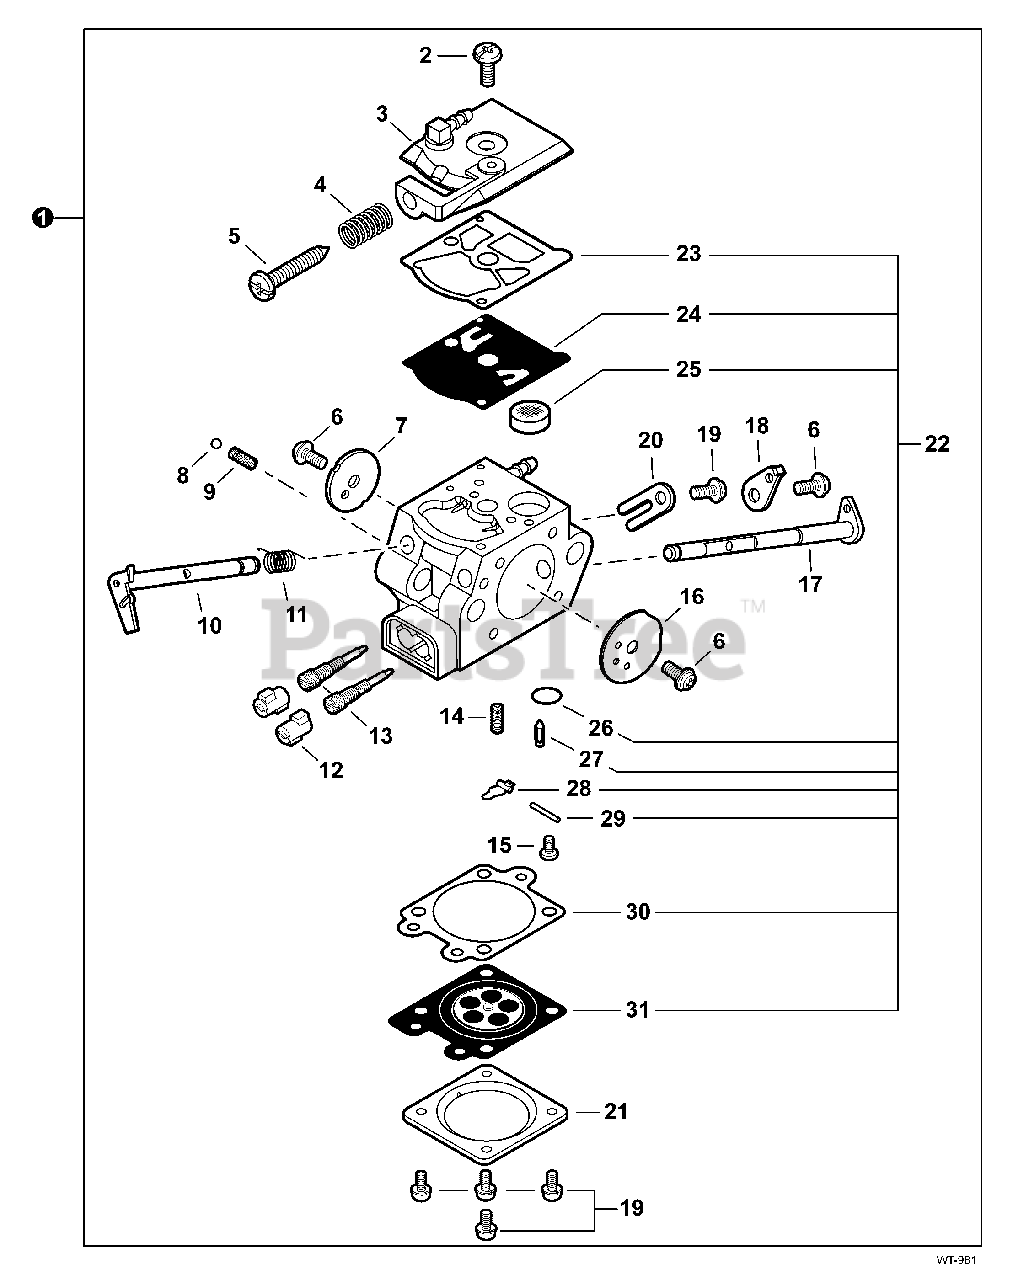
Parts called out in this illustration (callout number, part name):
1	CARBURETOR WT-981
3	+COVER, FUEL PUMP
4	+SPRING, IDLE ADJUST
5	+SCREW, IDLE ADJUST
7	+VALVE, THROTTLE
8	+BALL, CHOKE FRICTION
10	+SHAFT ASSY, THROTTLE
11	+SPRING, THROTTLE RETURN
12	+CAP, LIMITER
13	+NEEDLE, MIXTURE
14	+SPRING, METERING LEVER
15	+SCREW, METERING LEVER PIN
16	+VALVE, CHOKE
17	+SHAFT, CHOKE
18	+LEVER, THROTTLE
20	+CLIP, THROTTLE SHAFT
21	+COVER, METERING DIAPHRAGM
22	+REPAIR KIT, CARBURETOR
